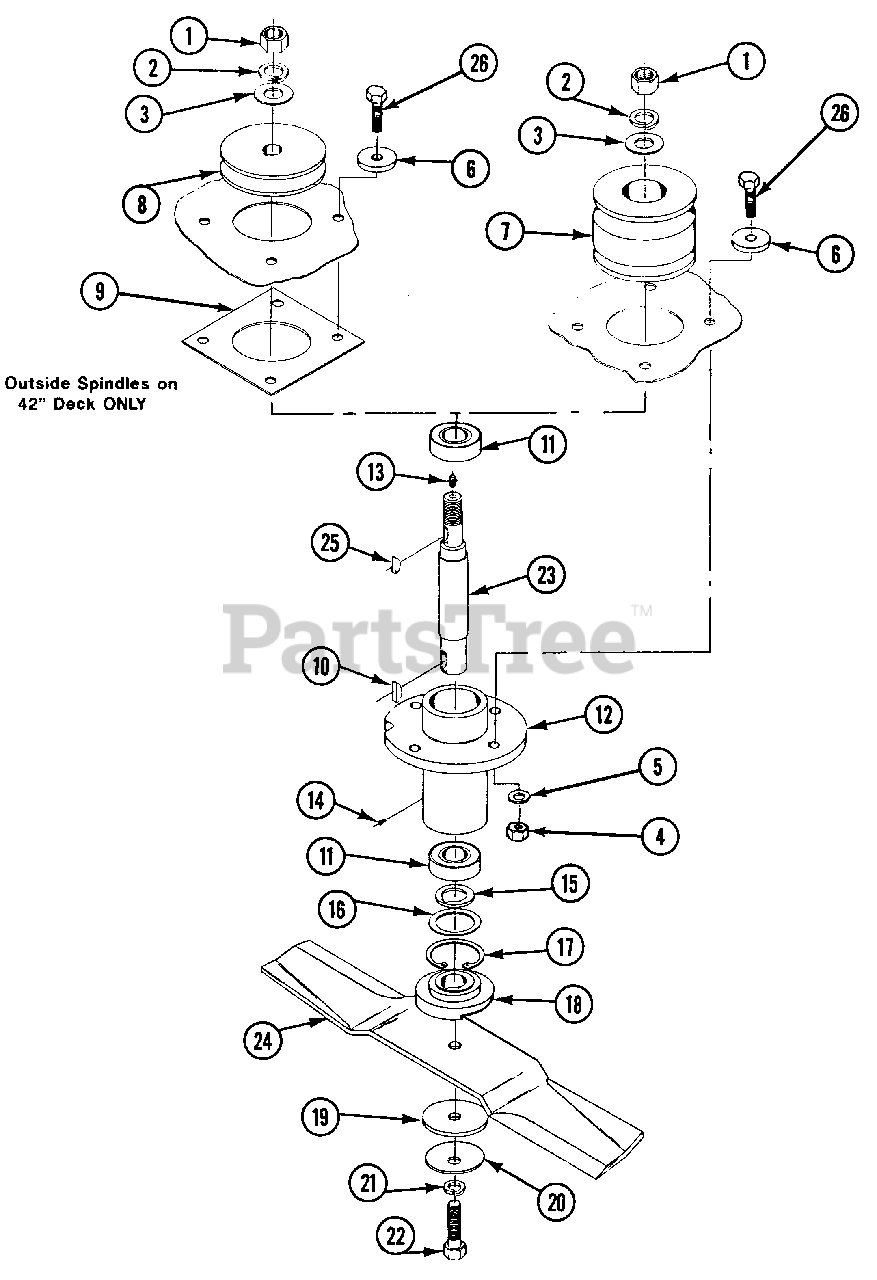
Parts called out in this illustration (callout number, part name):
1	NUTS HEX JAM, 3/4-16 UNF
2	LOCKWASHER, 3/4 STD, SPLIT SPRING
3	WASHER, 3/4 FLAT, TYPE B NARROW
4	LOCKNUT, HEX, 3/8-24
5	LOCKWASHER 3/8 HEAVY SPRING TYPE
6	SPINDLE SPACER REINFORCEMENT
7	PULLEY, 2 GROOVE, 4" OD (42" DECK)
7	4-1/2" OD (48" DECK)
7	5-3/8" OD (60" DECK)
8	PULLEYS 1 GROOVE, 4" OD
9	SHIN, SPINDLE HOUSING
10	WOODRUFF KEYS 1/4 X 3/4
11	BEARINGS 1" BORE, 2" OD, 1/2 WIDE
12	SPINDLE HOUSING
13	GREASE FITTING, 1/4-28, SELF-TAP
14	SCREW, ROUND HEAD, DRIVE #4 X 3/16
15	SPACER, ARBORS 3/32 THICK, 1" BORE
16	SEAL WASHER
17	SNAP RING, INTERNAL, 2"
18	BLADE SPACER, 2-1/2 BLADES
19	WASHER FLAT .515 ID, 2-1/2 OD
20	CUPPED WASHER, 1/2"
21	LOCKWASHER, 1/2 STD, SPLIT SPRING
22	CAPSCREW, HEX, 1/2-13 X 1-1/2, GRADE 5
23	SHAFT, BLADE SPINDLE
24	BLADE, LOW LIFT, 15" CUT (42" DECK)
24	BLADE, HIGH LIFT, 17" CUT (48" DECK)
24	BLADE, HIGH LIFTS 21" CUT (60" DECK)
25	WOODRUFF KEY, 3/16 X 5/8
26	CAPSCREW, HEX, 3/8-24 X 1-1/2, GRADE 5
